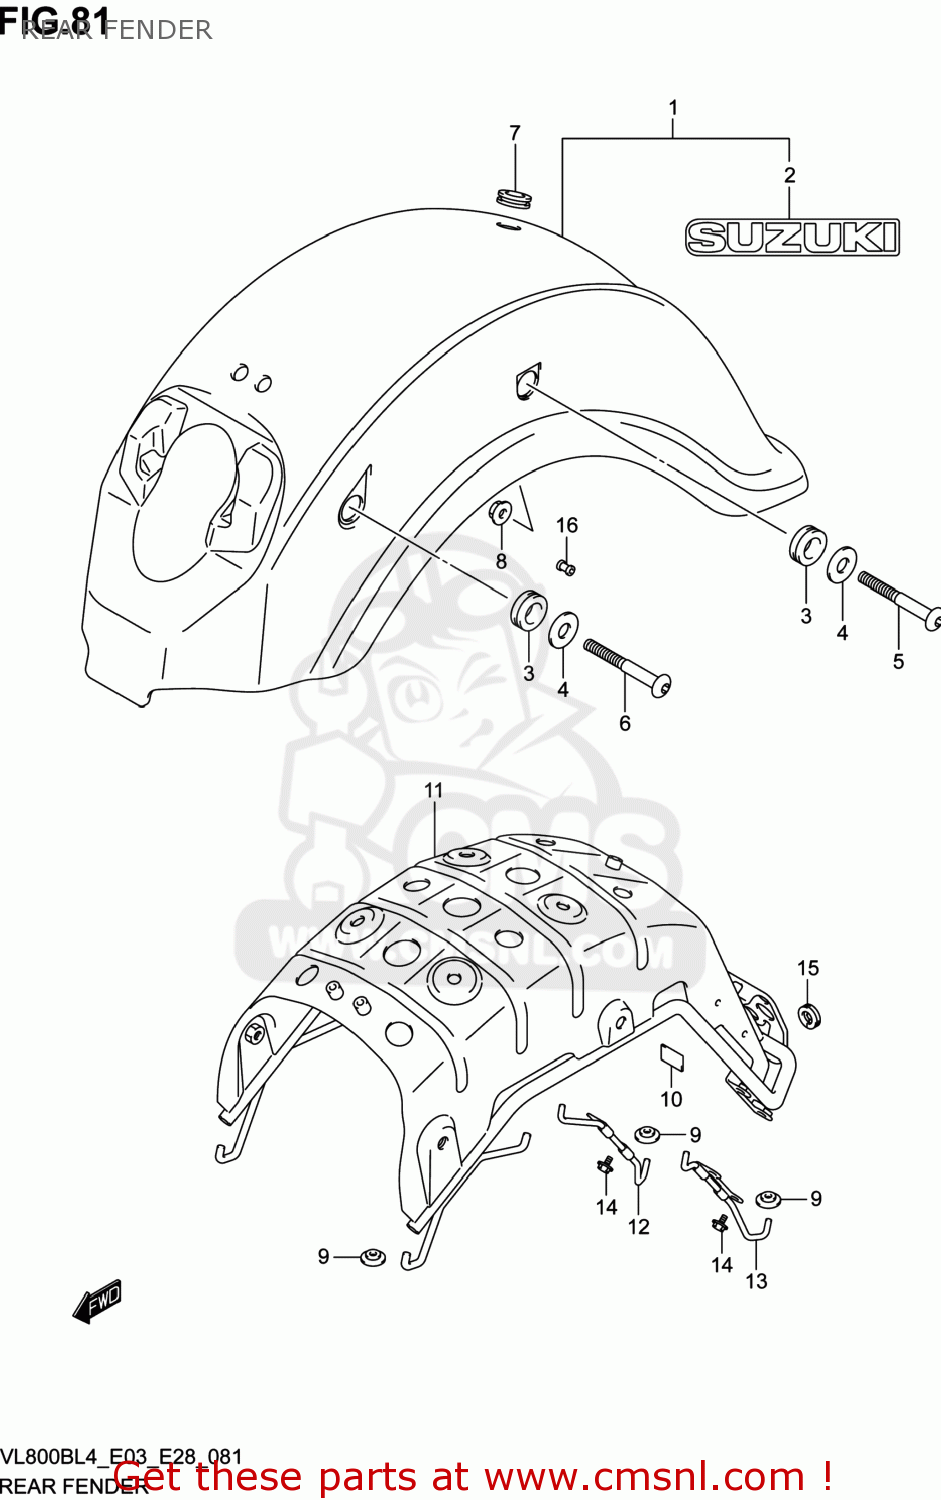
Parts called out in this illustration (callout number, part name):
1	FENDER,REAR
2	EMBLEM,SUZUKI
3	CUSHION,FRAME COVER UPR RR
4	WASHER(15.5X26X2.3)
5	BOLT,RR FENDER
6	BOLT,REAR FENDER FR
7	CUSHION
8	NUT
9	CUSHION
10	CUSHION,FR FENDER
11	REINF,RR FENDER
12	BRACKET,RR FENDER LWR,R
13	BRACKET,RR FENDER LWR,L
14	BOLT
15	GROMMET
16	PLUG(OD:9)
